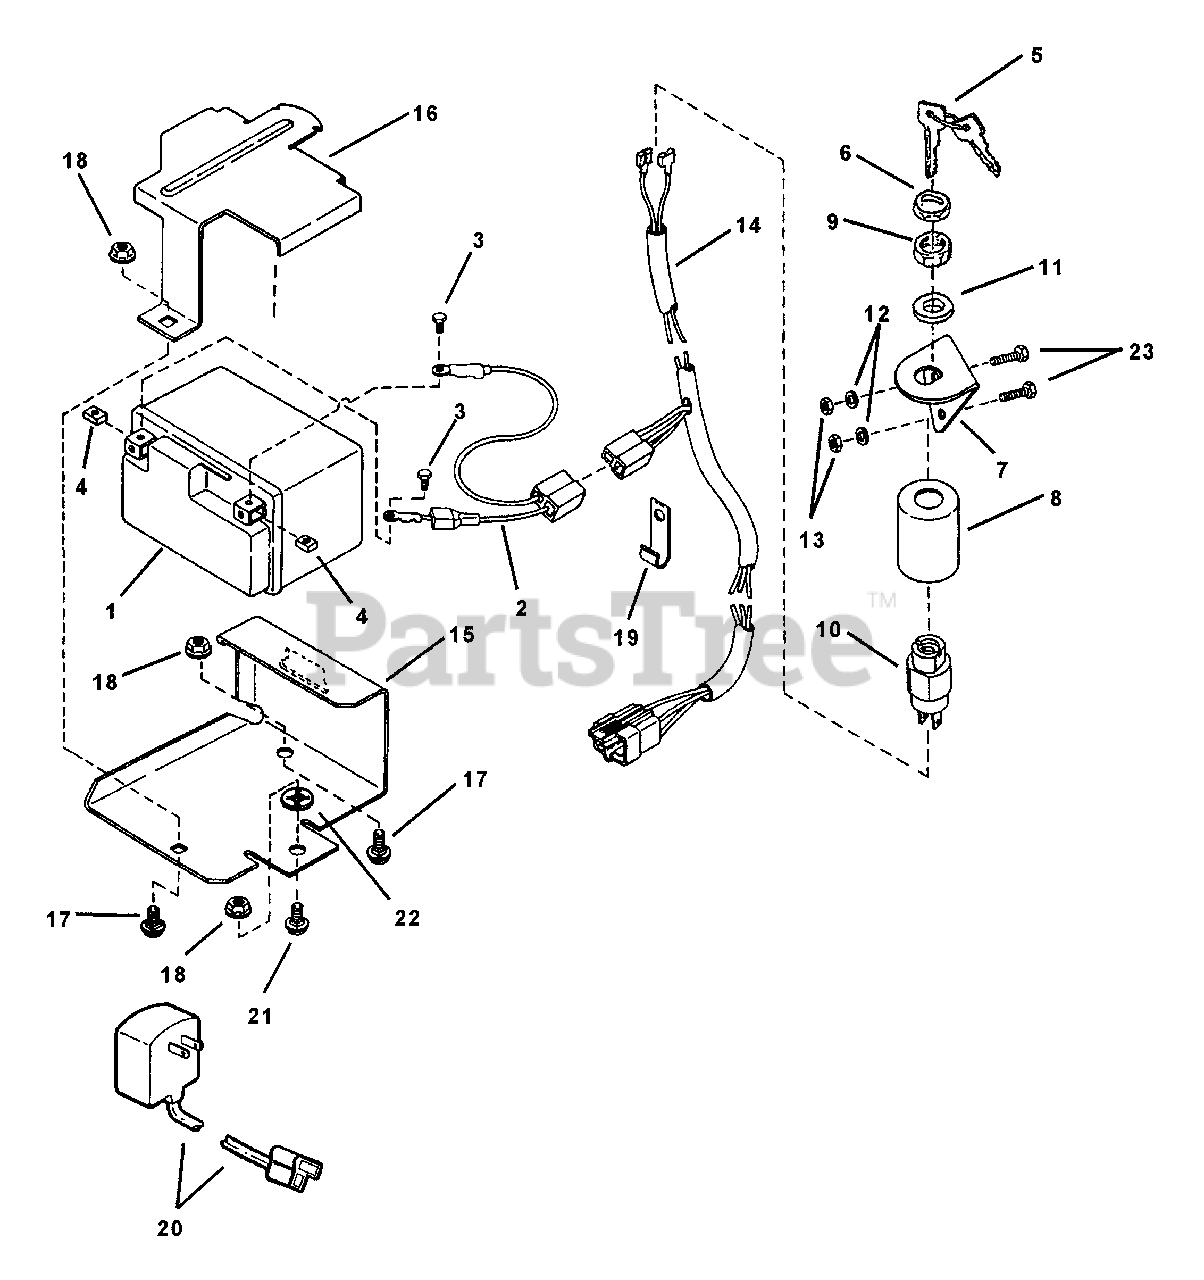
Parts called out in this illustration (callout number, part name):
1	BATTERY, 12 Volt, 35 CCA
2	HARNESS, Battery
3	SCREW, #10-24 x 1/2 Hex Head Cap
4	NUT, #10 24 Square
5	KEY, (Set of Two)
6	BEZEL
7	BRACKET, Ignition Switch
8	COVER, Switch
9	NUT, 3/4-20 Hex Lock
10	SWITCH, Ignition
11	SPACER
12	WASHER, 1/4 Internal Tooth Lock
13	NUT, 1/4-28 Hex Grade 5 or B
14	HARNESS, Wiring
15	BRACKET, Battery
16	COVER, Battery
17	BOLT, 5/16-18 x 1/2 Short Nk. Carriage, Gr. 5
18	NUT, 5/16-18 Hex Flange Lock Grade 5
19	CLIP, Wiring
20	CHARGER, Battery (120 Volt - 60 Hertz)
20	CHARGER, Battery (230 Volt - 50 Hertz)
21	BOLT, 5/16-18 x 5/8" Short Nk. Carriage, Gr. 5
22	RETAINER, 5/16 Bolt
23	SCREW, 1/4-28 x 1-3/8 Hex Head Cap, Gr. 5
